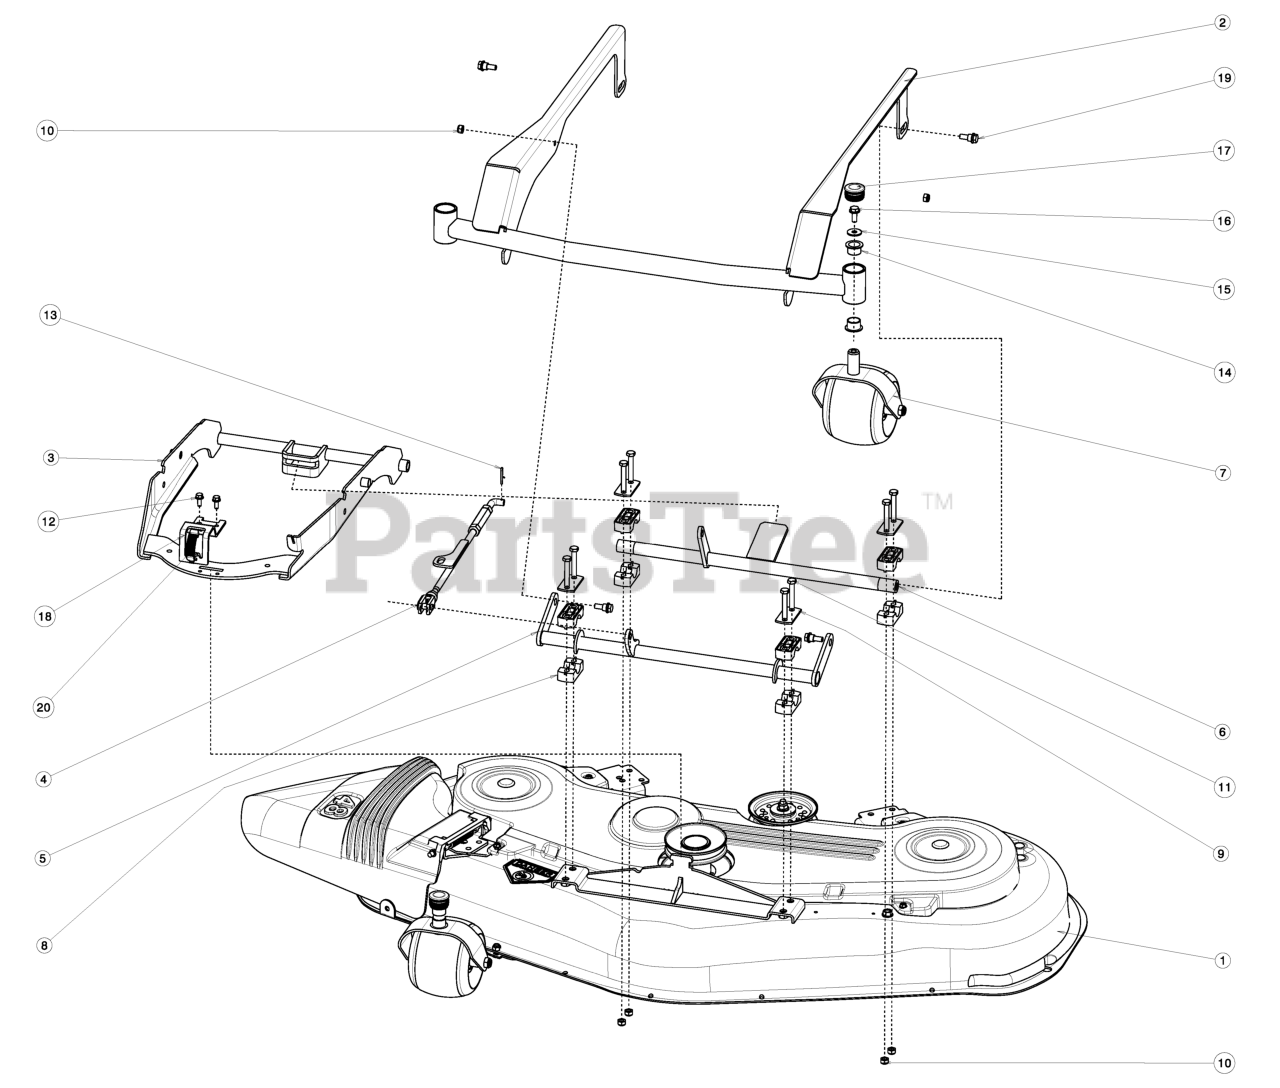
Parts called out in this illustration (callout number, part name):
2	FRAME.48"STMPD DECK.WLDT GRAY.
3	DECK ATTACHMENT
4	ROD.PARALLEL
5	CROSSBAR.FRONT.48"NA.STMPD.GRA
6	CROSSBAR.REAR.48"NA.STMPD.GREY
7	PIVOT WHEEL ASSY
10	LOCKNUT M8
12	SCREW
14	BUSHING FLANGE.79
20	CLIP GRAY
